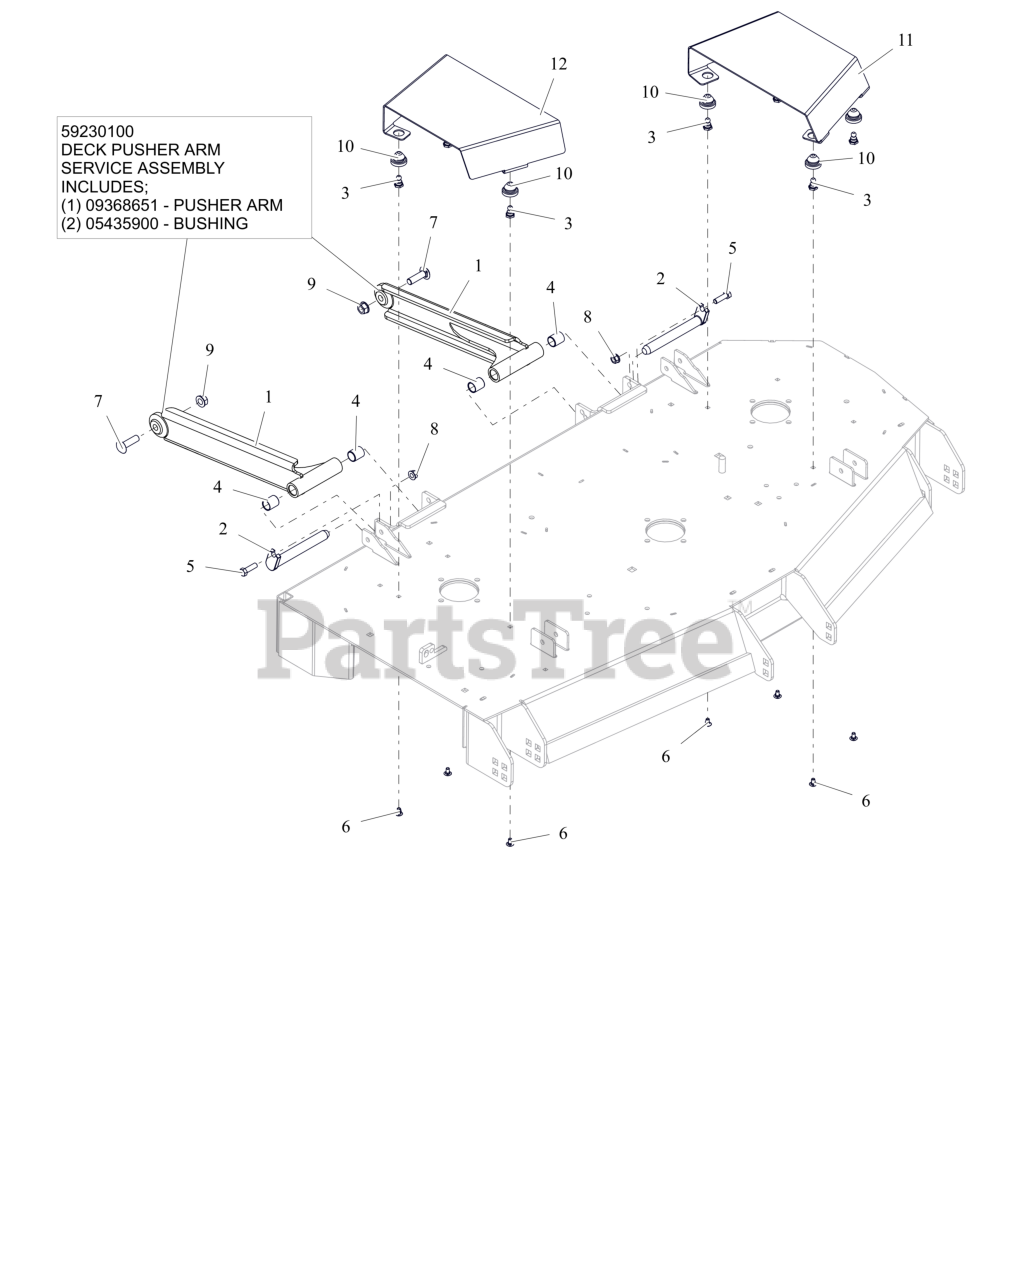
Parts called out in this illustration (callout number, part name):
1	WLDMT, DECK STABILIZER ARM (BLACK)
1	DECK PUSHER ARM SERVICE ASSEMBLY
1	BRG, .750 X .875 X 1.000
2	PIN, MOWER MTG
3	STUD, BALL FEMALE .250-20 THREAD
4	BRG, .750 X .875 X 1.000
5	BLT, HEX .38-16X1.25 G5 ZCC
6	BLT, RHSSN.25-20X.500 G5 ZCC
7	BTL,RHSSN .500-13 X 1.75 G5 ZCC
8	NUT-LK-CTR-FLG .375-16 GF ZCC
9	NUT-LK-CTR-FLG .500-13 GG ZCC
10	COUPLING, RUBBER PUSH-IN
11	GUARD, LH DECK BELT (RED)
12	GUARD, RH DECK BELT (RED)
